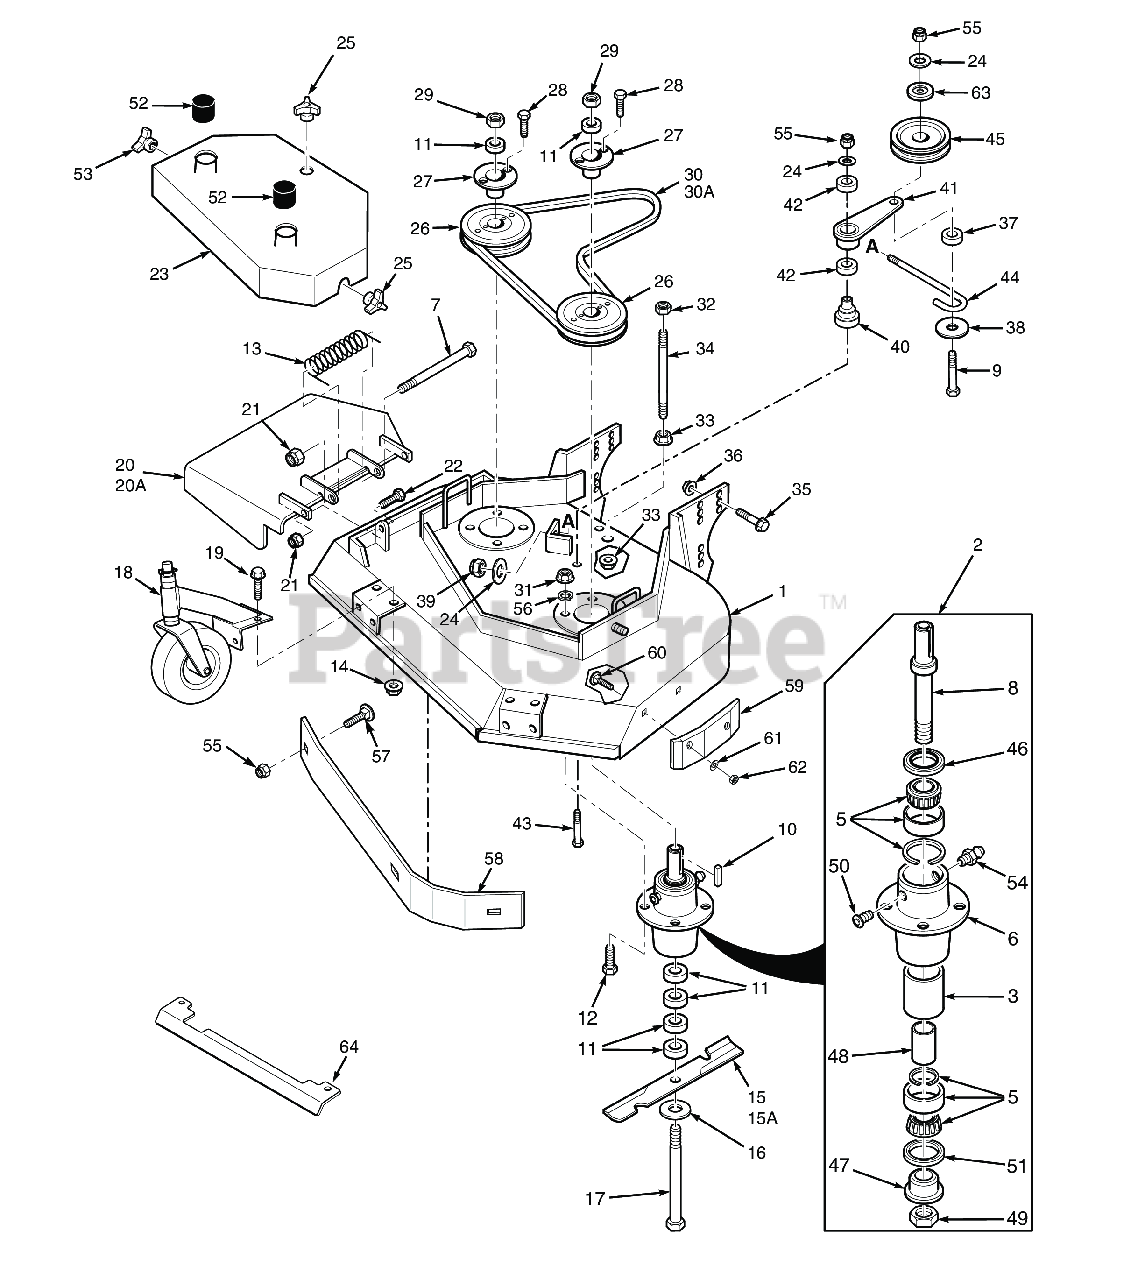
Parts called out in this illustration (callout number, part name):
1	Cutter Deck w/Decals
2	Cutter Spindle Assembly
3	Spacer, Outside, Cutter Spindle
5	Tapered Bearing Set (Two Bearings W/Race)
6	Housing, Spindle
7	Bolt, 5/16-18 x 4-3/4" Hex Head
8	Spindle Shaft, Tapered Brng
9	Capscrew, Hex Head 3/8-16 x 3-3/4"
10	Key, 1/4 x 1/4 x 2.0"
11	Spacer, Cutter Blade - Small
12	Bolt, Hex Head 5/16-18 x 1-1/2" Grade 8
13	Spring, Discharge Chute
14	Nut, Serrated Flange 5/16-18 (Right Front Engine Mounting, Briggs and Kohler Only)
15	Cutter Blade 18" (marbane)
15A	Cutter Blade 18" Hi Lift (marbane)
16	Flatwasher, 5/8-.688 x 1-3/4 x .134 HD
17	BOLT, HEX HEAD, 5/8-11 X 9-1/2 GR.5
18	Caster Assembly
19	Capscrew, 5/16-18 x .75 Serrated Flange Hex Head
20	Discharge Chute Advantage - Small
21	HEX NUT, ELASTIC STOP LOCK, 5/16-18
22	Bolt, Heax Head 5/16-18 x 1" (48V / 52V)
23	Belt Cover Assy (Incl. Decal)
24	Flatwasher, 3/8 (.391 x .938 x .105 HD) Grade 8
25	WINGNUT, PLASTIC 3/8-16 X .875
26	Pulley, 5.75 O.D. (Gasoline Engines)
27	Hub, Tapered 1-1/8" Bore
28	Bolt, Hex Head 1/4-20 x 1" Grade 8 Black
29	Hex Locknut, Elastic Stop, 3/8-16
30	BELT CUTTER DK SM36
31	Lock Nut, 5/16-18 Elastic Stop Grade 8
32	Bolt, Hex Head 3/8-16 x 1" Ser. Flg.
33	NUT, 3/8-16 SERRATED FLANGE HEX HEAD
34	Bolt, 5/16-18 x 1" Hex Head
35	Serr. Fl. Hex Head Capscrew, 1/2-13 x 1-3/4
36	Nut, Elastic Stop 1/2-13, (STT-52 & STTII-52)
37	SPACER, J-PULL ROD
38	Flatwasher, 3/8 (.375 x 1-1/2" x 16 ga.)
39	HEX NUT, ELASTIC STOP LOCK, 3/8-16
40	Pivot, Idler - Short
41	Idler Arm Assy.
42	BEARINGS, BALL, NEUTRAL RETURN
43	Capscrew, Hex Head 3/8-16 x 3.25"
44	J-Hook, Idler Pulley
45	Idler Pulley, Belt Clutch
46	SEAL, 2.00 O.D. X 1.50 BORE
47	SPINDLE BUSHING, BOTTOM
48	SLEEVE, CUTTER SPINDLE
49	Nut , Spec ial 1 -1/ 1 6 - 1 8
50	RELIEF FITTING, TAPERED BEARING SPINDLE
51	Seal, 2.00" O.D. x 1.625" Bore
53	Wing Nut, 3/8-16 (Small) Top side
54	GREASE FITTING, STR. 1/4-28 SELF TAP.
55	HEX NUT, ELASTIC STOP LOCK, 3/8-16
56	Lockwasher, 5/16 (.317 x .586 x .078) Helical Spring
57	Carriage Bolt, 3/8-16 x 1.0"
58	Baffle, Flange - 36A
59	Pad, Deck Wear
60	Bolt, 5/16-18 x .75 RHSN Carriage
61	Flatwasher, 5/16-.344 x .688 x .065 (48V / 52V)
62	Nut, Center Lock, 5/16-18(32)
63	Quick Pin, 5/16" Dia.
64	Heatshield, 16" Small Frame
